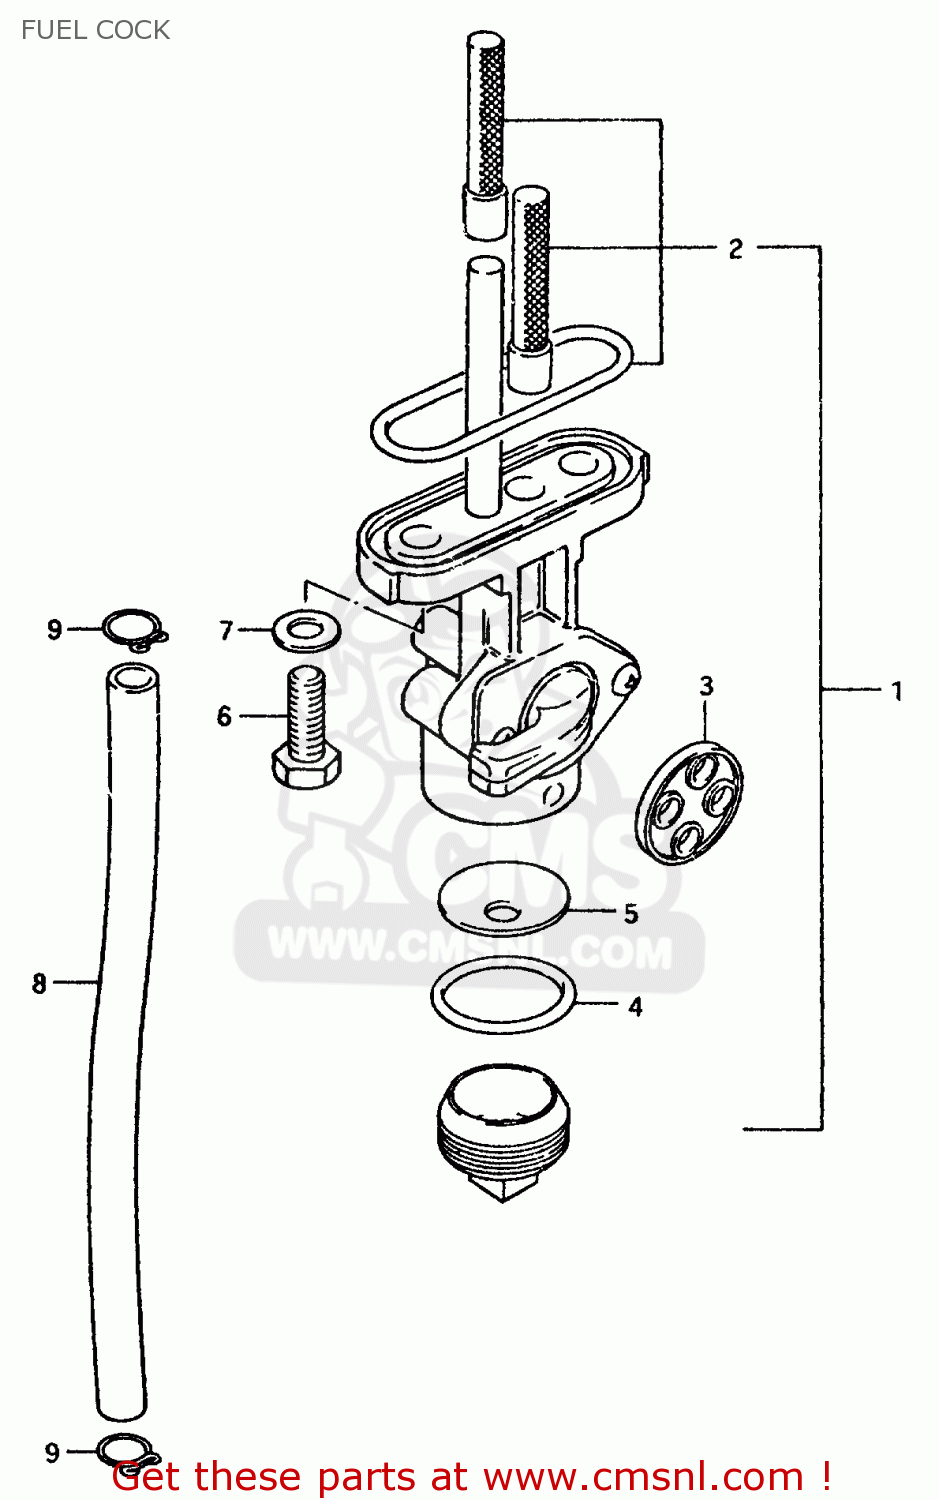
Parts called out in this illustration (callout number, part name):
1	COCK ASSEMBLY,FUEL
2	FILTER SET,FUEL COCK
3	GASKET,LEVER (NAS)
4	GASKET,FILTER (NAS)
5	NET,STRAINER
6	BOLT(6X20)
7	GASKET
8	HOSE
9	CLIP
